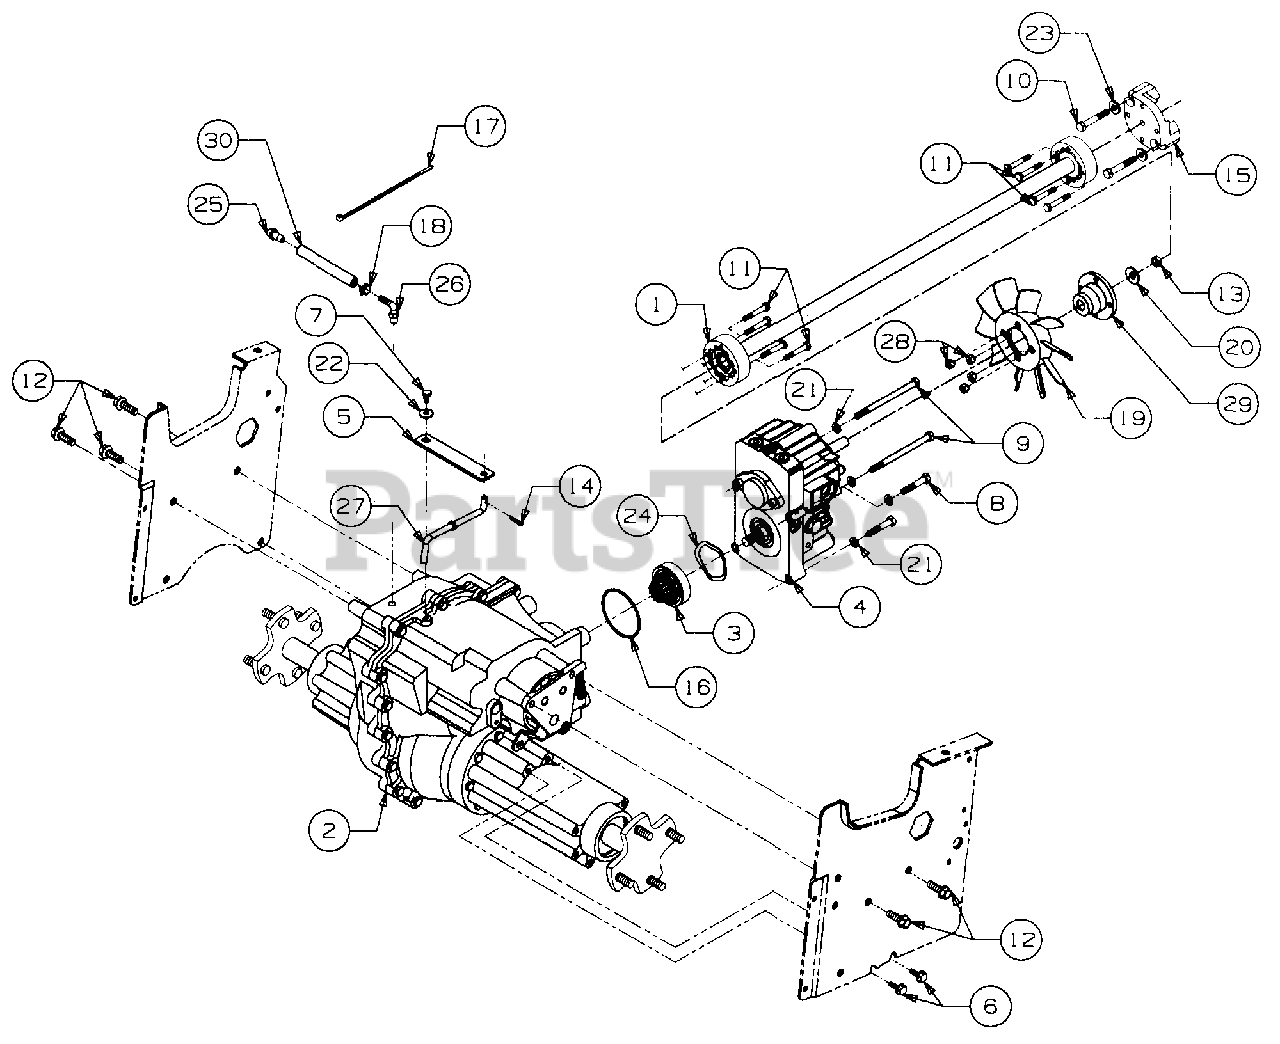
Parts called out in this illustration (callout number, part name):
1	Shaft Assy, Drive, 27.87 transmission Lg
2	Transmission, Hydro
3	Pinion Assy
4	Pump, Hydrostatic
5	Arm, Hydro Dump
6	Screw, Hex Wash Sf-Tapp, 5/16-18 x .75 Lg
7	Screw, Hex Wash TT-Tapp, 1/4-20 x .75 Lg GR5
8	Screw, Hex Cap, 5/16-18 x 1.75 Lg GR5
9	Screw, Hex Cap, 5/16-18 x 4.5 Lg GR5
10	Bolt, Hex Patch, M8-1.25 x 50mm
11	Bolt, Hex Patch, 1/4-20 x 1.62 Lg GR5
12	Screw, Hex Wash Tapp, 3/8-16 x 1.25 Lg
13	Nut, Hex Center Lock Jam, 3/8-24
14	Pin, Internal Cotter, 5/16 Dia x 1.12 Lg
15	Adapter, Drive Shaft
16	O-Ring, 2.75 x .103
17	Tie, Self-Clinch Cable
18	Clamp, Hose
19	Fan, 10 Blade Cooling
20	Washer, Bell, .380 x .88 x .062 Thk
21	Washer,Lock, 5/16
22	Washer, Bell, .265 X.75 x .062 Thk
23	Washer, Flat, .312 x .750 x .119 Thk
24	Washer Spring Wave, 1.96 x 2.44 x .06 Thk
26	Fitting, Elbow
27	Rod, Hydro Disengagement
28	Nut, Fan, 1/4-20
29	Adapter, Pump
30	Line, Fuel, 7 in. Lg
